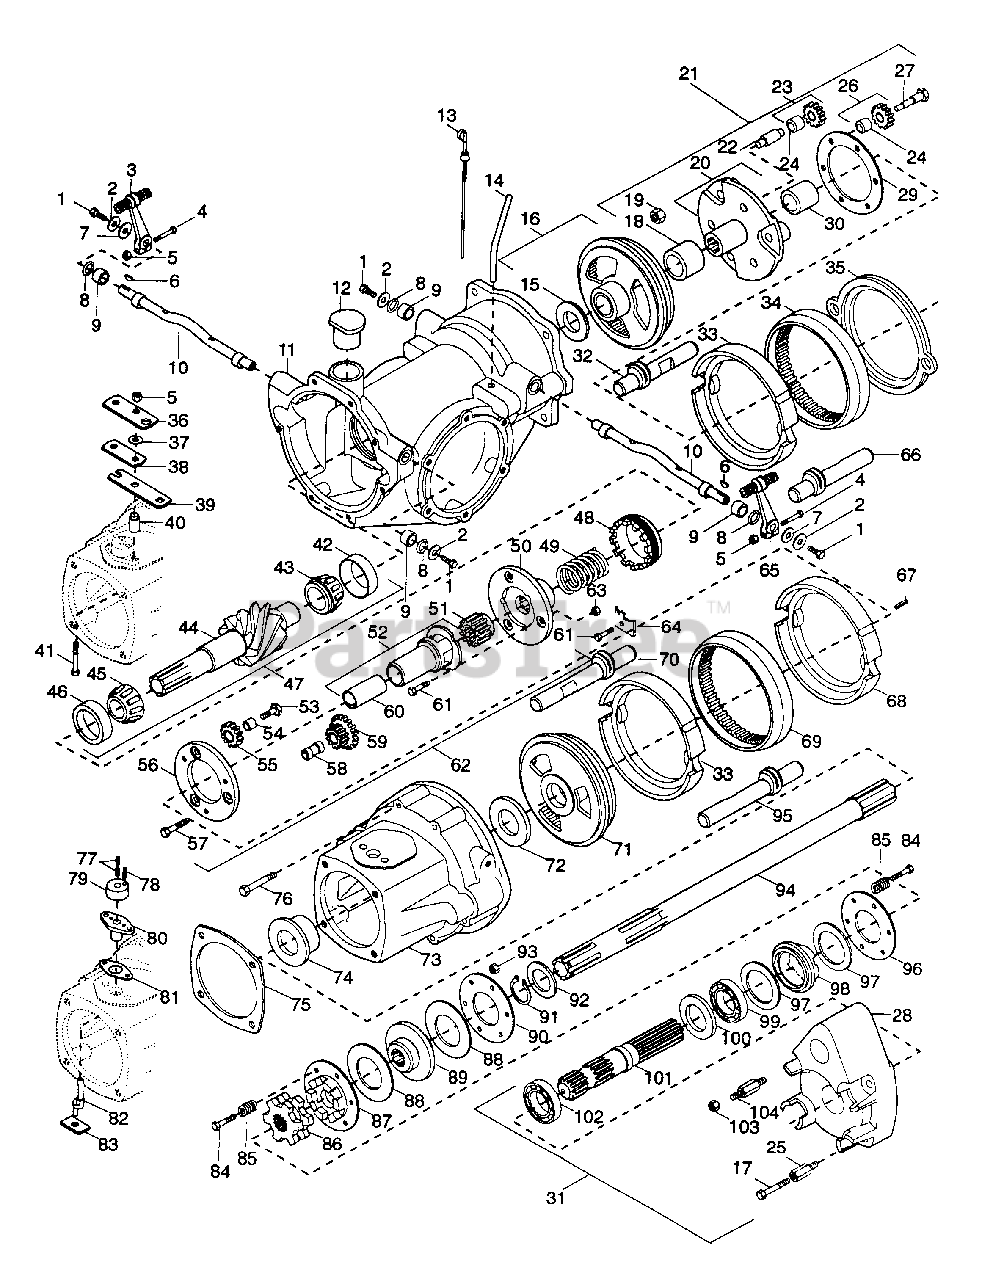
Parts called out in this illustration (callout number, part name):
1	BLT-HEX .25-20 X .50 PL GR 5
2	WSHR-FL-STL .281 X 1.250 X .062 PL
3	ASM, FWD-REV LEVER
4	BLT-HEX .31-18 X 2.00 PL GR 5
5	NUT-LK-NYL .312-18 PL
6	KEY, WDRF .13 X .63 HRD #5
7	WSHR-FLAT .812 X 1.469 X .134
8	O-RING .75 X 1.0
9	BUSH., 5.749 X 1.00 X .625 ST
10	SHFT, ACTUATING
11	CHS
12	PLUG, OIL FILTER
13	ASM, DIP STICK
14	GUIDE, DIP STICK
15	PLT, REAR THRUST
16	ASM, RING GR & BUSH
17	BLT-HEX .50-13 X 1 PL GR 5
18	BSH-SLV 1.125 X 1.5 OZ X 1.312
19	NUT-LK .312-18 X .265 L.H.
20	ASM, PLANET GEAR CARRIER
21	ASM, HI-LO PLANETARY
22	PIN, HI-LO ORBIT GEAR
23	ASM, INTERNAL ORBIT GEAR
24	BSHG-SLV .500 X .627 X .465 BR
25	STUD, QUICK HITCH
26	ASM, EXTERNAL ORBIT GEAR
27	BLT, ORBIT GEAR
28	CSTNG, QUICK HITCH
29	SPLR, PIN
30	BSHG-SLV .737 X .877 X .683 BRZ
31	QUICK HITCH ASSEMBLY
32	ROD, REAR RH CLUTCH SLIDE
33	ASM, CLUTCH CUP
34	GR, REAR RING
35	SPLR, REAR
36	BRKT, PTO SWITCH
37	WSHR-FL-STL .344 X .688 X .065
38	SPLR, STRAP
39	ARM, SHIFTER
40	BUSH., F .344 X .562 X .866 ST
41	BLT-HEX .31-18 X 2.50 PL GR 5
42	BRG-CUP 2.328 X .465
43	BRG-CONE 1.25 X .66
44	WLDMT, 6-LEAD WORM
44	WLDMT, 8-LEAD WORM
45	BRG-CONE 1.250 X 2.875
46	BRG-CUP .688 X 2.875
47	WLD WRM SHFT ASM 6 LEAD
47	WLD WRM SHFT ASM 8 LEAD
48	NUT-BRG 3.00-16 CL
49	SG-COMP .188 X 1.66 X 2.0
50	PLT, FRONT PIN
51	GR, SUN PINION SPUR
52	ASM, QUILL AND BUSHING
53	BLT .38-24 X .860
54	BUSH., 5.375 X .686 X .516 ST
55	GR, REVERSE IDLER SPUR
56	SPLR, FRONT PIN
57	BLT-SPLR .38-16 X 1.81
58	PIN, FWD-REV ORB GR STL
59	GR, ORBIT SPUR
60	BSHG-SLV .875 X 1.002 X 2.015 BR
61	BLT-HEX .25-20 X .63
62	ASM, FWD-REV PLANETARY
63	NUT-HEX .250-20 ZC
64	NUT, ADJUSTING
65	ASM, HI-LO LEVER
66	ROD, REAR LH CLUTCH SLIDE
67	PIN-ROLL .368 X .500
68	CUP, GEAR
69	INTERNAL SPUR
70	ROD, L.H. CLUTCH SLIDE
71	CONE REVERSE GEAR
72	DISK, FRICTION
73	ASM, ADVANCE CASTING
74	BSHG-FLG 1.375 X 1.628 X .957 X 2.12
75	GSKT, ATTACHMENT
76	BLT-HEX .31-18 X 3.25 GR 8 PL
77	SCP-SET .38-16 X .25 HSLKT
78	PIN, ROL .250 X .75
79	BODY, SHIPPER SHAFT
80	SHIPPER SHAFT(NYLON)
80	GD, SHIPPER SHAFT(CAST IRON
81	GSKT, SHIPPER SHAFT
82	SHFT, SHIPPER
83	BLOCK, TRUNION
84	BLT-HEX .31-24 X 1.75
85	SG-COMP .156 X .343 X .75 WLD
86	DOG
87	PLT, DOG
88	WSHR, FRICTION
89	PLT, DRIVE
90	PLT, BACK
91	RG-RTNG-EXT .875 X .042
92	WSHR-THRST .877 X 1.427 X .632
93	NUT-JAM .312-24 PL
94	SHFT, PINION
95	ROD, R.H. CLUTCH SLIDE
96	PLT, BACK
97	DISC, BRAKE
98	BRK, DOG PLATE
99	BRG-BALL .984 X 2.047 X .591
100	SEAL 1.102 X 2.047 X .315
101	SHFT, QUICK HITCH
102	BRG-BALL .984 X 2.04 X .59
103	NUT .50-13 PL
104	STUD, QUICK HITCH
